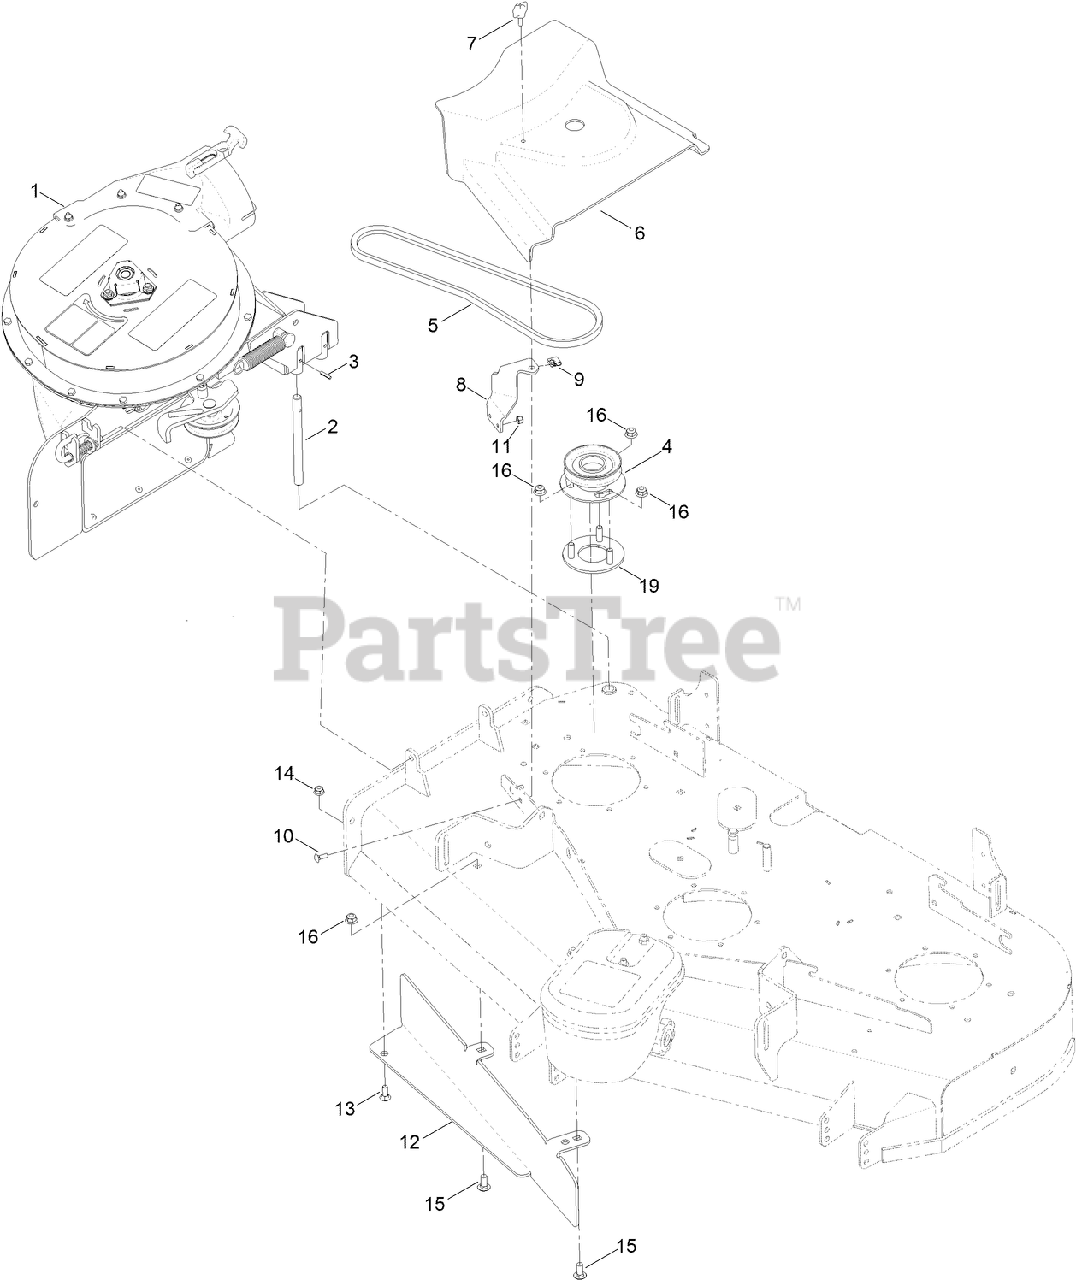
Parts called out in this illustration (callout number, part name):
1	BLOWER ASM
2	SHAFT-CATCHER, GRASS
3	PIN-ROLL
4	PULLEY ASM
5	BELT-V
6	COVER-BELT
8	BRACKET-COVER, BELT
9	NUT-SPEED
10	BOLT-CARR
11	NUT-LOCK, NI
12	BAFFLE-BAGGER
13	SCREW-CARR
14	NUT-HF, NI
15	SCREW-CARR
16	NUT-HF, NI
19	MOUNT-PULLEY
